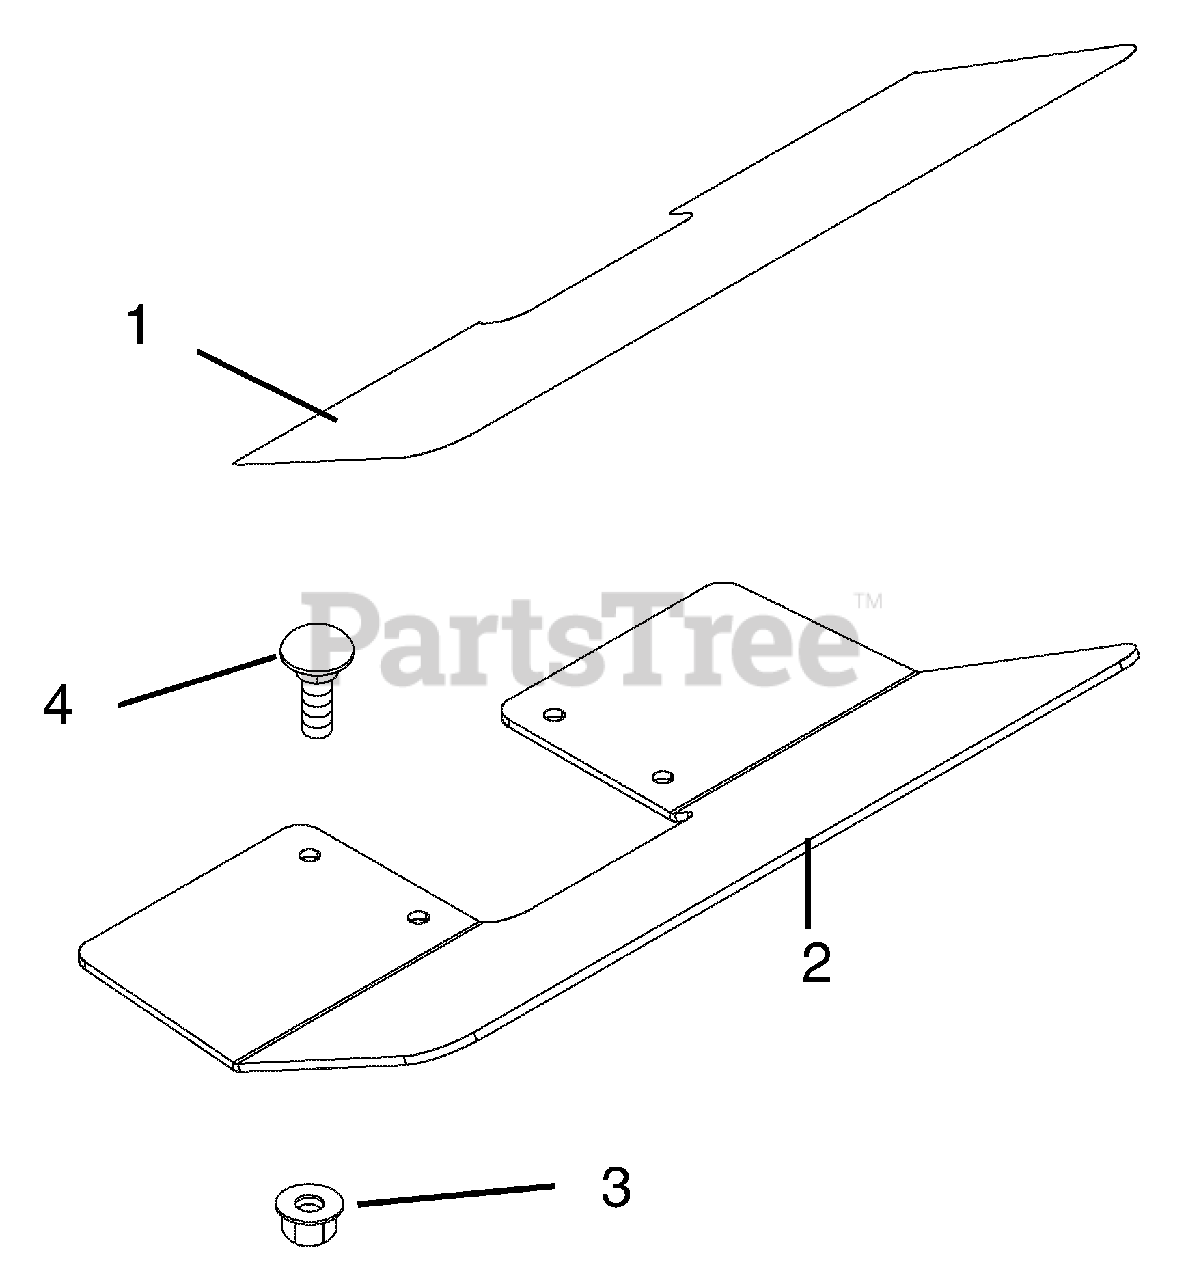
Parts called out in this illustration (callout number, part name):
1	Footrest Extension Grip
2	Footrest Extension Bracket
3	3/8" Nylon Flange Locknut
4	3/8" x 1" Round Head Square Neck Bolt
